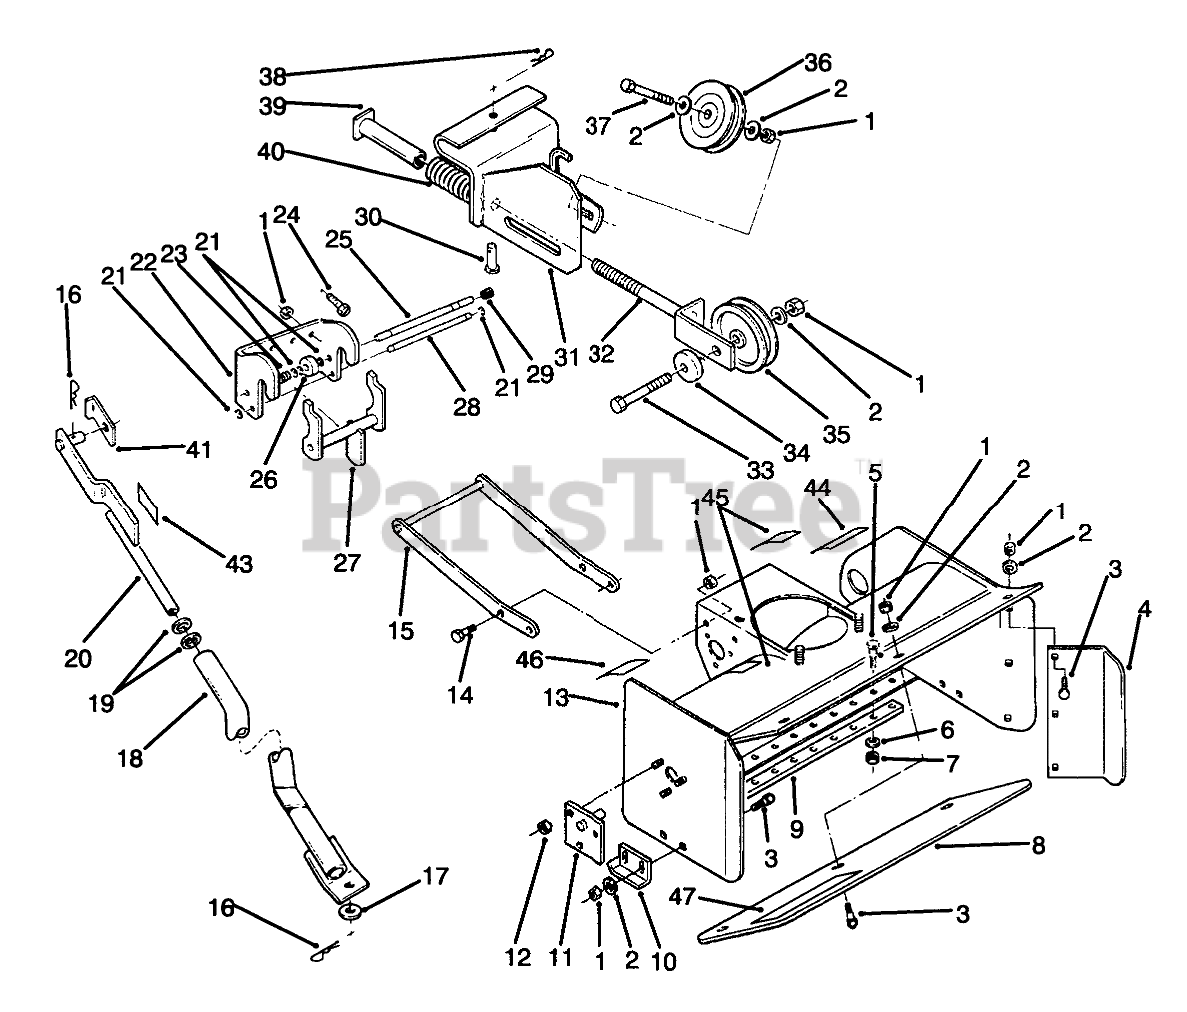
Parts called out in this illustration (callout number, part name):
1	NUT-LOCK, NI
2	WASHER-FLAT
3	BOLT-CARR
4	PLATE-EXTENSION, RH
5	SCREW-CARR
6	WASHER-FLAT
7	NUT-LOCK, NI
8	PLATE-EXTENSION
9	SCRAPER-REVERSIBLE
11	SUPPORT
12	NUT-LOCK, NI
13	Housing-Auger (Incl. Ref. #44-46)
14	SCREW-HH
16	Hairpin
17	WASHER-FLAT
18	LIFT ROD
19	WASHER
20	Rod-Lift (Incl. Ref. #43)
21	RING-RETAINING
22	Housing-Front Hitch
23	SPRING
24	SCREW-CARR
25	ROD-LOCK
27	LATCH
28	ROD-LATCH PIVOT
29	CAP-ROD, PLUNGER
30	CLEVIS PIN
31	BRACKET IDLER W.A.BLK
32	IDLER-SLIDE W.A.
33	SCREW-HH
34	BUSHING
35	PULLEY-IDLER, FLAT
36	PULLEY-IDLER
37	SCREW-HH
38	Hairpin Cotter
39	SPRING-TENSIONER
40	Spring-Compression
41	RETAINER CLIP
43	DECAL - WARNING
44	DECAL - WARNING
45	DECAL-DANGER
46	DECAL-WARNING
47	DECAL-ATTACHMENT
